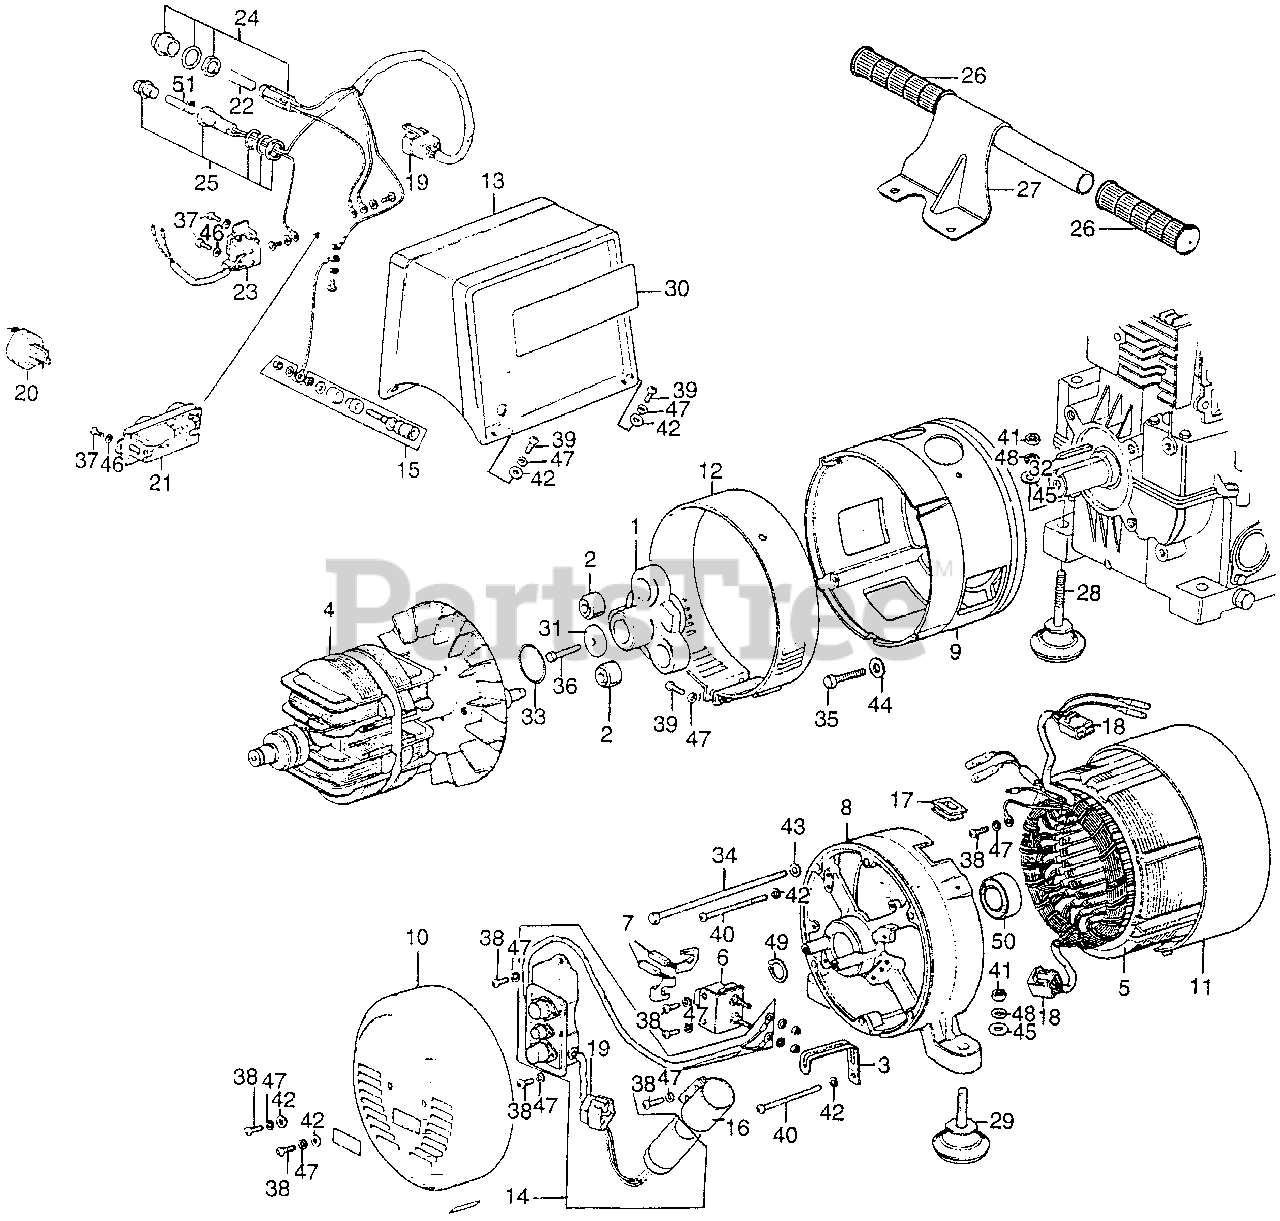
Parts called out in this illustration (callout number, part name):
1	FLANGE, COUPLING
2	RUBBER, COUPLING
3	CLAMP A, WIRE
5	STATOR ASSY.
6	HOLDER, BRUSH
8	HOUSING, RR. *R8* (BRIGHT RED)
9	HOUSING, FR. *R8* (BRIGHT RED)
10	COVER, GENERATOR END *R8* (BRIGHT RED)
11	COVER, STATOR *R8* (BRIGHT RED)
12	COVER, FAN *R8* (BRIGHT RED)
13	BOX, CONTROL *R8* (BRIGHT RED)
14	REGULATOR ASSY., AUTOMATIC VOLTAGE (NOT AVAILABLE)
15	TERMINAL ASSY., GROUND (NOT AVAILABLE)
18	CONNECTOR, FEMALE (4 POLE)
19	CONNECTOR, MALE (4 POLE)
20	PLUG ASSY., RECEPTACLE
21	RECEPTACLE (15A-125V)
22	BULB (24V2W)
23	METER, FREQUENCY
24	SOCKET ASSY., PILOT LAMP (NOT AVAILABLE)
25	HOLDER ASSY., FUSE
26	GRIP B, L. HANDLEBAR
27	HANDLE, CARRYING
28	RUBBER (LOWER) (NOT AVAILABLE)
29	RUBBER (LOWER) (NOT AVAILABLE)
30	PLATE, CAUTION (NOT AVAILABLE)
31	WASHER (8MM)
32	KEY (7X7X33)
33	O-RING (35.5X3) (NOK)
34	BOLT, HEX. (6X142) (SOURCE: VINTAGE PARTS INC.)
35	BOLT, HEX. (8X25)
36	BOLT, HEX. (8X32)
37	SCREW, PAN (4X10)
38	SCREW, PAN (5X10)
39	SCREW, PAN (5X16)
40	SCREW, PAN (5X55) (NOT AVAILABLE)
41	NUT, HEX. (10MM)
42	WASHER, PLAIN (5MM)
43	WASHER, PLAIN (6MM)
44	WASHER, PLAIN (8MM)
45	WASHER, PLAIN (10MM)
46	WASHER, SPRING (4MM)
47	WASHER, SPRING (5MM)
48	WASHER, SPRING (8MM)
49	CIRCLIP (OUTER) (17MM)
50	BEARING, RADIAL BALL (6203UU)
51	FUSE A (15A)
